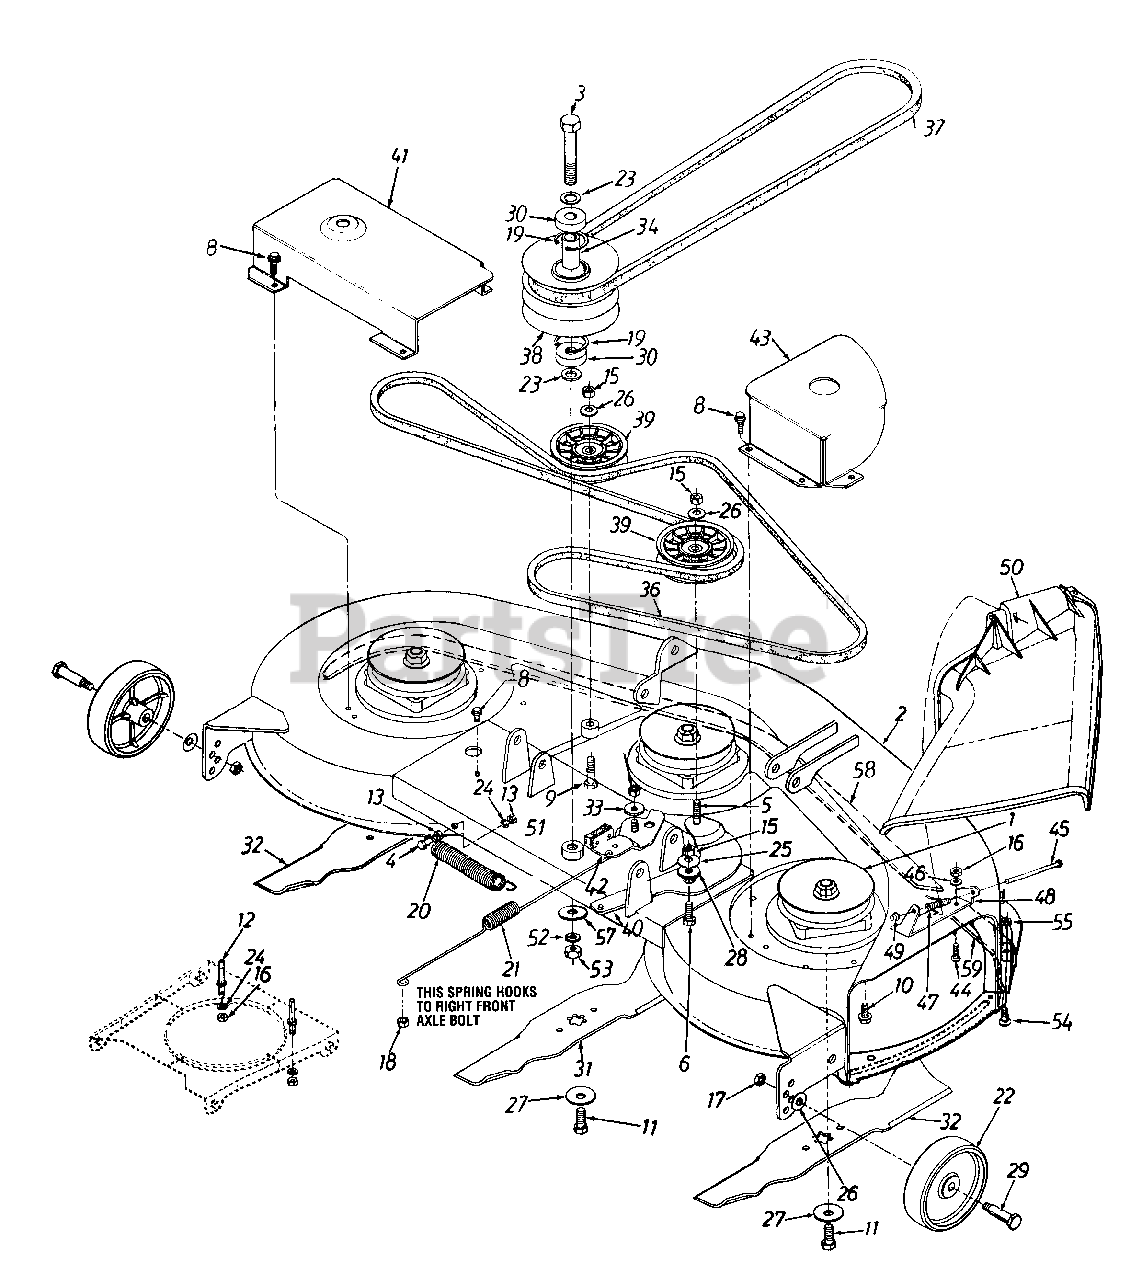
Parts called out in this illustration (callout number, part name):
1	Blade Spindle Ass'y.
4	Hex Bolt 1/4-28 x 1.25" Lg.
5	Hex Bolt 3/8-24 x 1.5" Lg.
6	Hex Bolt 3/8-24 x 1" Lg.
8	Hex Wash. Hd. TT-Tap Scr. 1/4-20 x .5" Lg.
9	Hex Bolt 3/8-24 x 2" Lg.
10	Hex Flange Bolt 5/16-24 x .75" Lg.
11	Hex Patch L-Bolt 7/16-20 x 1" Lg.
12	Belt Guard Pin
13	Hex Nut 1/4-28 Thd.
15	Hex Nut 3/8-24 Thd.
16	Hex Nut 1/4-20 Thd. (Gr. 5)
17	Hex Top Jam Nut 3/8-16 Thd.
18	Hex Center L-Nut 5/16-18 Thd.
19	Int. Snap Ring
20	Ext. Spring .88" O.D. x 6.17"
21	Ext. Spring .788" O.D. x 15.5"
22	Deck Wheel
23	Fl-Wash. .635" I.D. x 1" O.D. x .06"
24	L-Wash. 1/4" I.D.
25	Bell-Wash. 3/8" x 1.125" x .062"
26	Bell-Wash. 3/8" x .87" x .064"
27	Bell-Washer
28	Shoulder Spacer .625" I.D. x .169"
29	Shld Bolt .498" x 1.525"
30	Ball Brg 625" I.D. x 1.574" O.D. x .47"
31	High Lift Blade 14.88" Lg.
32	High Lift Blade 16.28" Lg
33	Shoulder Spacer
34	Spacer .635" I.D. x .088" O.D.
36	V-Belt
37	V-Belt
38	Pulley Double Deck 5" O.D.
39	Flat Idler Pulley 3.5 O.D.
44	Hex Bolt 1/4-20 x 62" Lg.
45	Hinge Pin
46	Bell-Wash 1/4" I.D.
47	Torsion Spring
48	Hinge Mtg. Brkt
49	Push Nut
50	Chute Ass'y Comp.
51	Spacer .635" I.D. x 1" O.D.
52	L-Wash. 5/8" I.D.
53	Hex Nut 5/8-18 Thd.
54	Carriage Bolt 1/4-20 x .5" Lg.
55	Hex Sems Nut 1/4-20 Thd.
57	Fl-Wash. .635" I.D.
